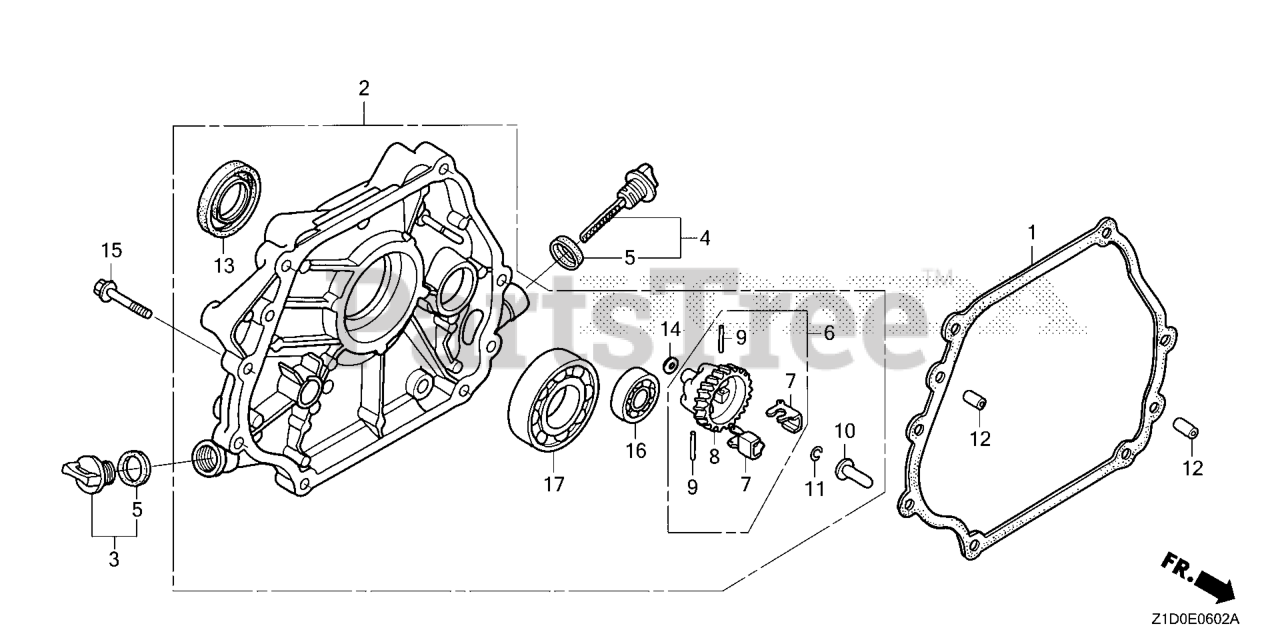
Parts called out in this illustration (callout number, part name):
1	GASKET, CASE COVER
2	COVER ASSY., CRANKCASE
3	CAP ASSY., OIL FILLER
4	CAP ASSY., OIL FILLER
5	GASKET, OIL FILLER CAP
6	GOVERNOR ASSY. (BALANCER)
7	WEIGHT, GOVERNOR
8	HOLDER, GOVERNOR WEIGHT
9	PIN, GOVERNOR WEIGHT
10	SLIDER, GOVERNOR
11	CLIP, GOVERNOR HOLDER
12	PIN, DOWEL (8X12)
13	OIL SEAL (30X46X8) (NOK ASIA)
14	WASHER, PLAIN (6MM)
15	BOLT, FLANGE (8X35)
16	BEARING, RADIAL BALL (6202)
17	BEARING, RADIAL BALL (6206)
